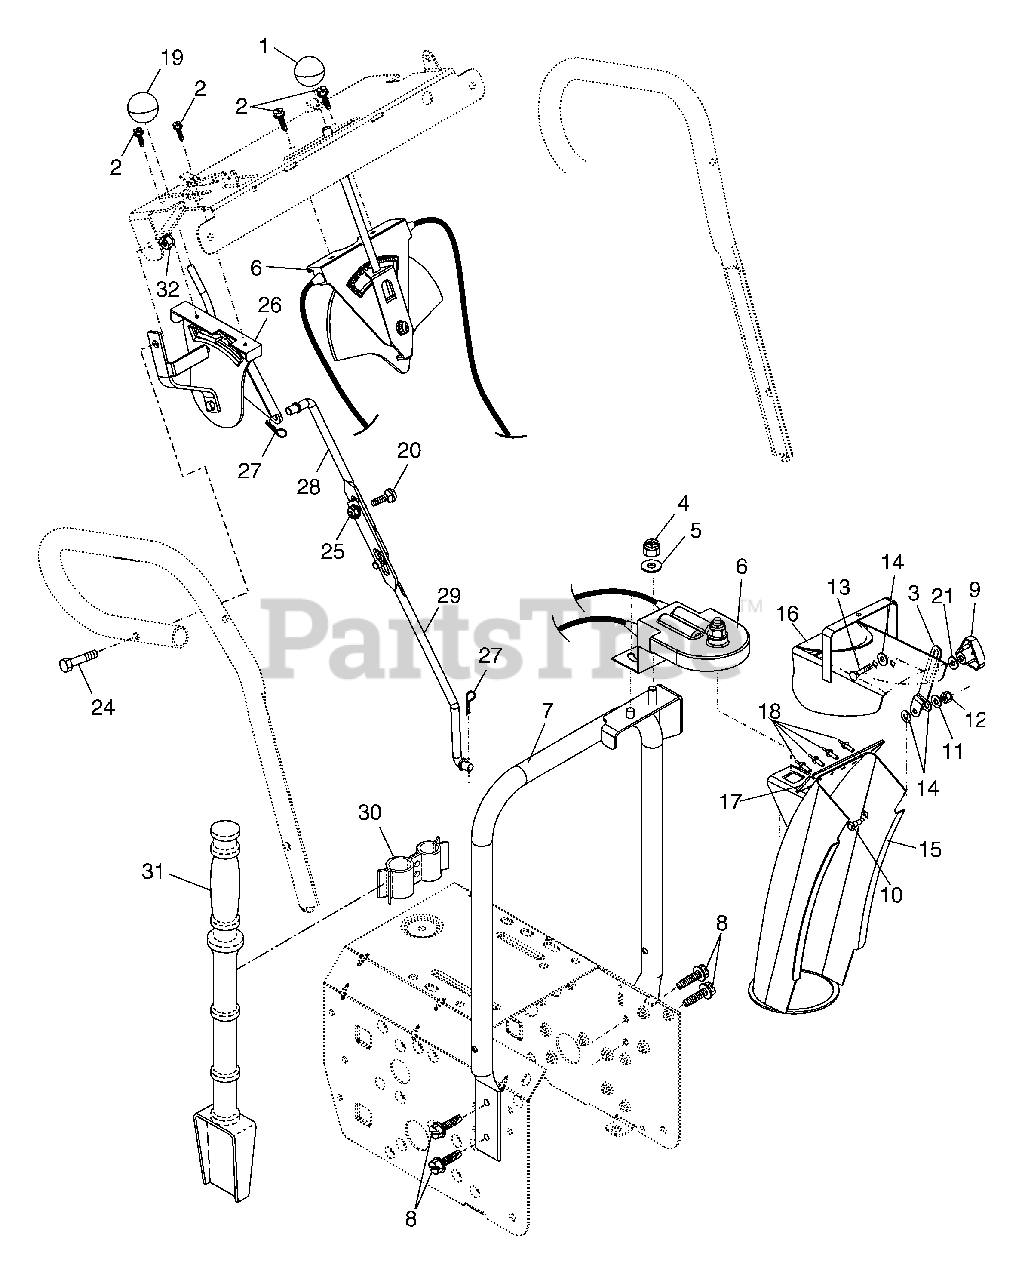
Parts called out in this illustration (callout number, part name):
1	Knob, Lever
2	Screw #10-24 x 5/8
3	Strap, Slotted
4	Nut, Lock 3/8-16
5	Washer, Flat 3/8
6	Control Assembly, Chute Rotater
7	Support, Pivot
8	Screw, Hex Head 5/16-18 x 3/4
9	Knob, Deflector
10	Bolt, Shoulder
11	Washer, Flat 1/4
12	Nut, Lock 1/4-20
13	Bolt, Carriage 5/16-18 x 5/8
14	Washer, Nylon
15	Chute Assembly
16	Deflector Assembly
17	Seal, Deflector
18	Rivet, Blind
19	Knob, Speed Control Lever
20	Bolt, Carriage 5/16-18 x 3/4
21	Washer, Flat
24	Screw, Hex Head 5/16-18 x 1-3/4
25	Nut, Lock 5/16-18
26	Lever Assembly, Speed Control
27	Retainer, Hairpin
28	Rod, Upper, Speed Control
29	Rod, Lower, Speed Control
30	Clamp, Clean-Out Tool
31	Tool, Clean-Out
32	Nut, Lock 5/16-18
